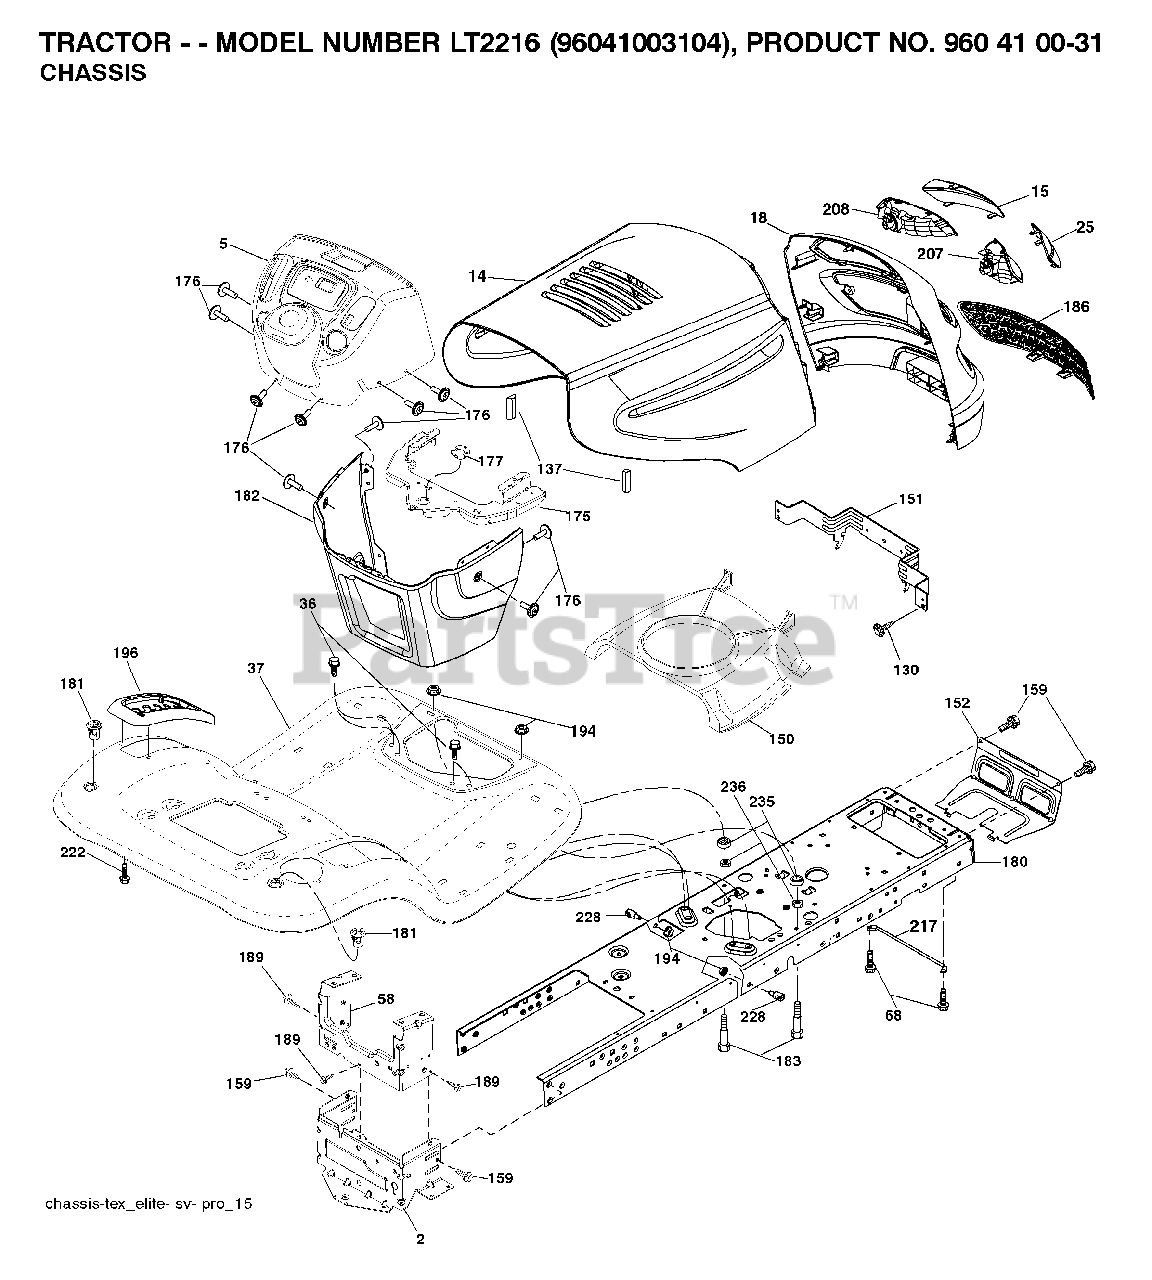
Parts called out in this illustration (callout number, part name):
2	DRAWBAR.LOWER.2PC.18/22
36	SCREW 5/16"
58	DRAWBAR UPPER 2PC SMALL FENDER
130	SCREW
137	BUMPER.HOOD.LARGE.1.75"
151	BRACKET PIVOT
152	SHIELD.BROWNING/DEBRIS
159	SCREW, 3/8-16X3/4
175	CROSSMEMBER.LT
176	SCREW.#10-24X5/8.RN.QU
177	BUSHING STEERING
180	CHASSIS.STAMPING.LT/GT
181	FEND/FTRST.PCH.CPH.NFW
182	DASH.LOWER.LT.CCS
183	BOLT.5/16-18X1-1/4 FULL.THREAD
189	SCREW
194	NUT LOCK HEX FLANGE 5/16-18
196	CONSOLE.ASM.DECK.LIFT.TLT.BLAC
207	BEZEL GRILL RH
208	BEZEL GRILL LH
217	ROD.PIVOT.HOOD
222	SCREW.1/4-20X5/8
228	STUD.FASTNER.W/ANTI-ROTATE
235	SPACER FENDER
236	NUT.CENTERLOCK.5/16-
